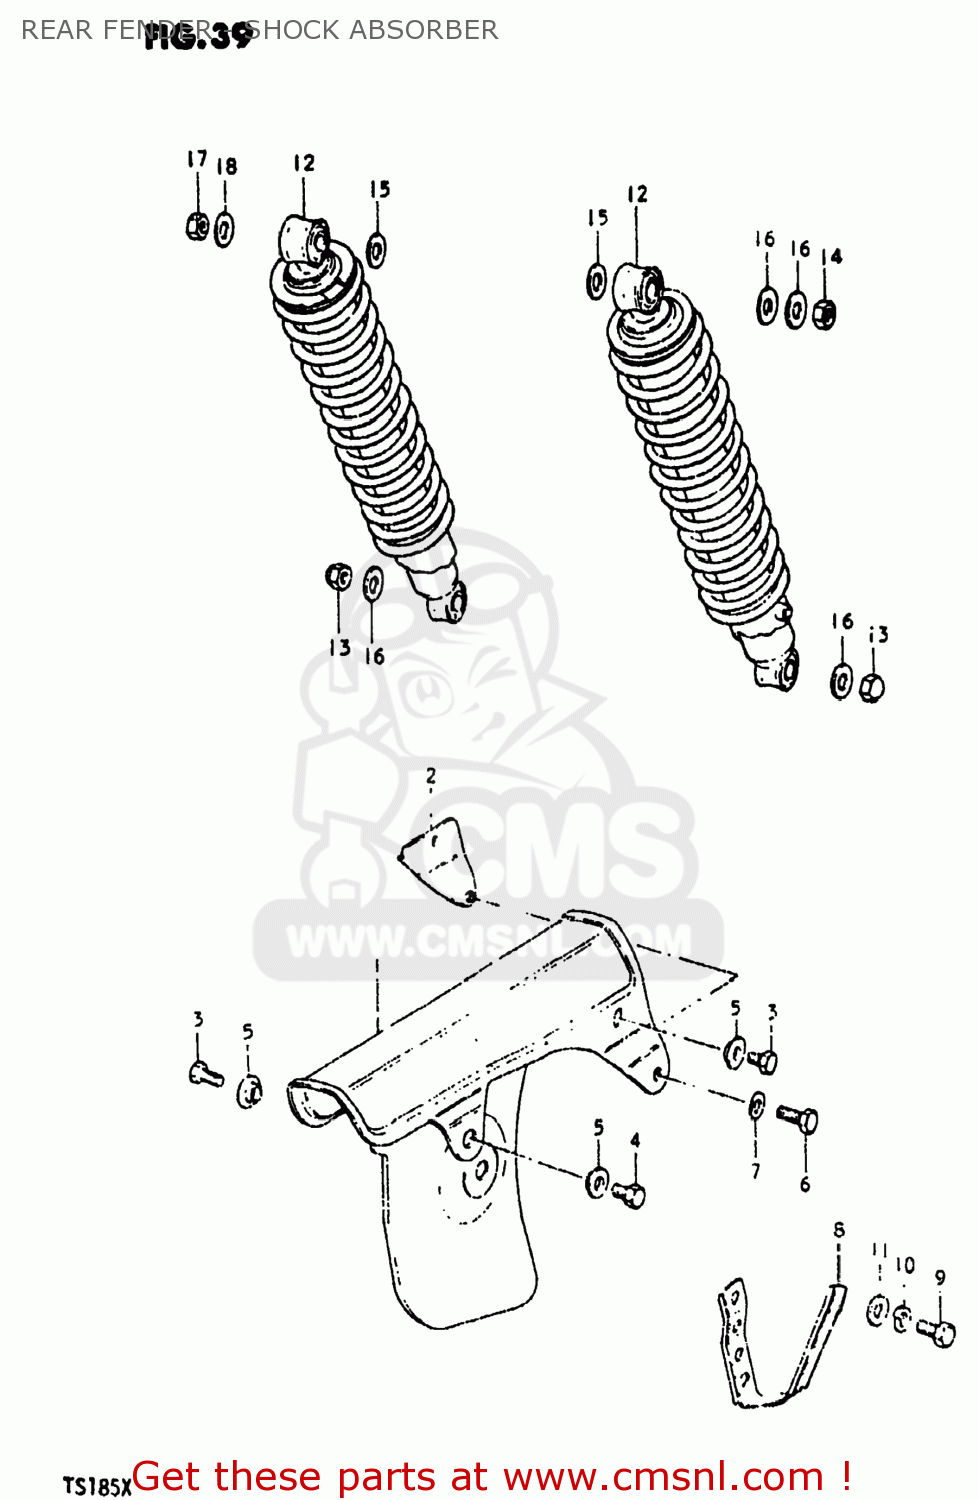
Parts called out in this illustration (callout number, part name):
1	CASE,CHAIN
2	REINFORCEMENT,CHAIN
3	BOLT(6X8)
4	BOLT
5	WASHER
6	BOLT, UPPER
7	WASHER
8	GUIDE,CHAIN
9	BOLT 8X12
10	LOCK WASHER
11	WASHER
12	ABSORBER ASSY,RR SHOCK
13	NUT, LOWER LH
14	NUT
15	WASHER
16	WASHER
17	NUT
18	WASHER (12.5X24X3.2)
